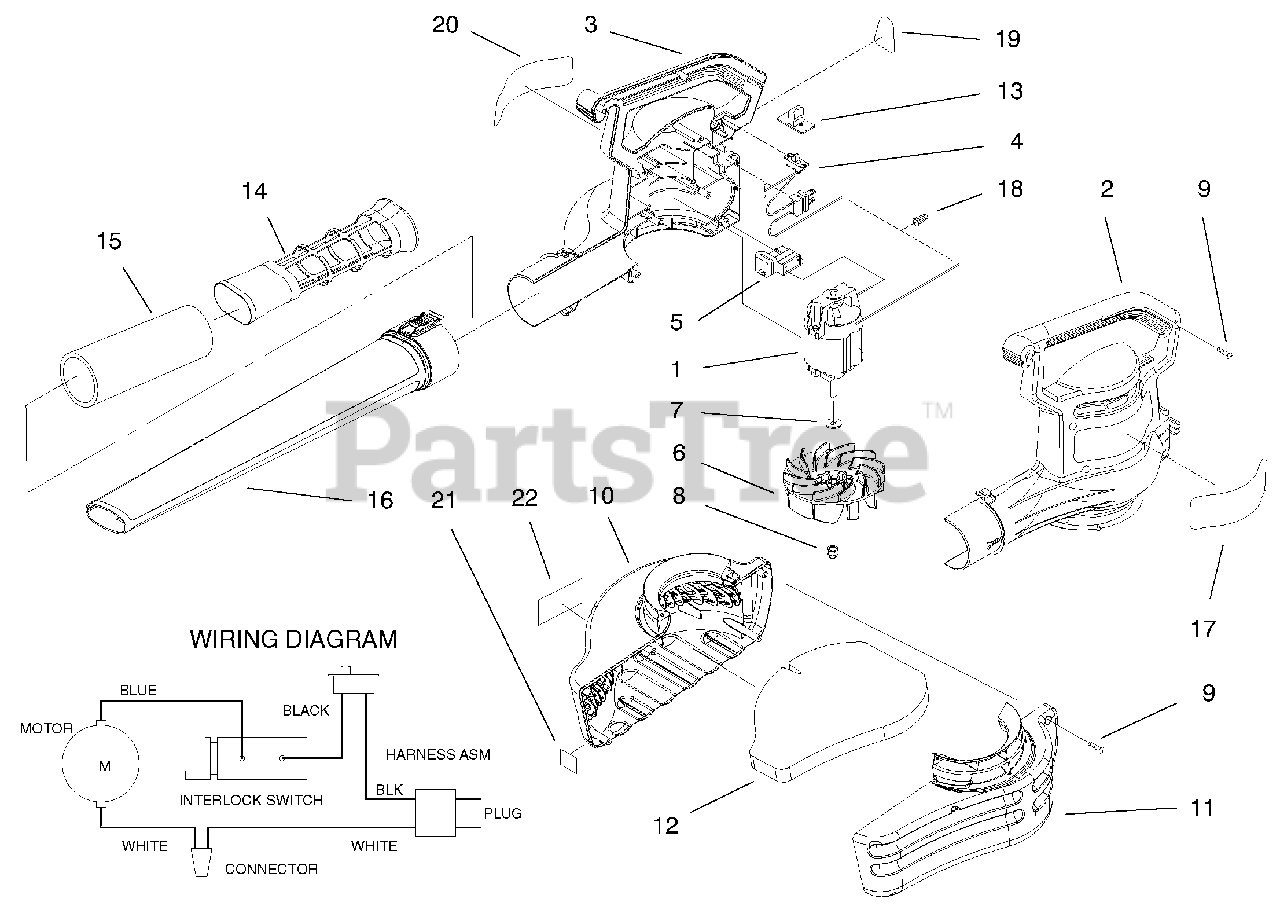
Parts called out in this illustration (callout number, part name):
2	Housing-L.H.
3	Housing-R.H.
4	Harness Assembly
5	Switch-Interlock
6	Impeller-Blower
8	Nut-Cap Hex
9	Screw-Phillips Hd. Tap.
10	Inlet-Quiet R.H.
11	Inlet-Quiet L.H.
12	Foam-Inlet
13	Cover-Switch
14	Insert-Quiet
15	Foam-Insert
16	Tube-Blower
17	Decal-Warning
18	Connector-Wire Nut
19	Decal-Information
20	Decal-Logo
21	Decal-63DBA
22	Decal-QuieTech
